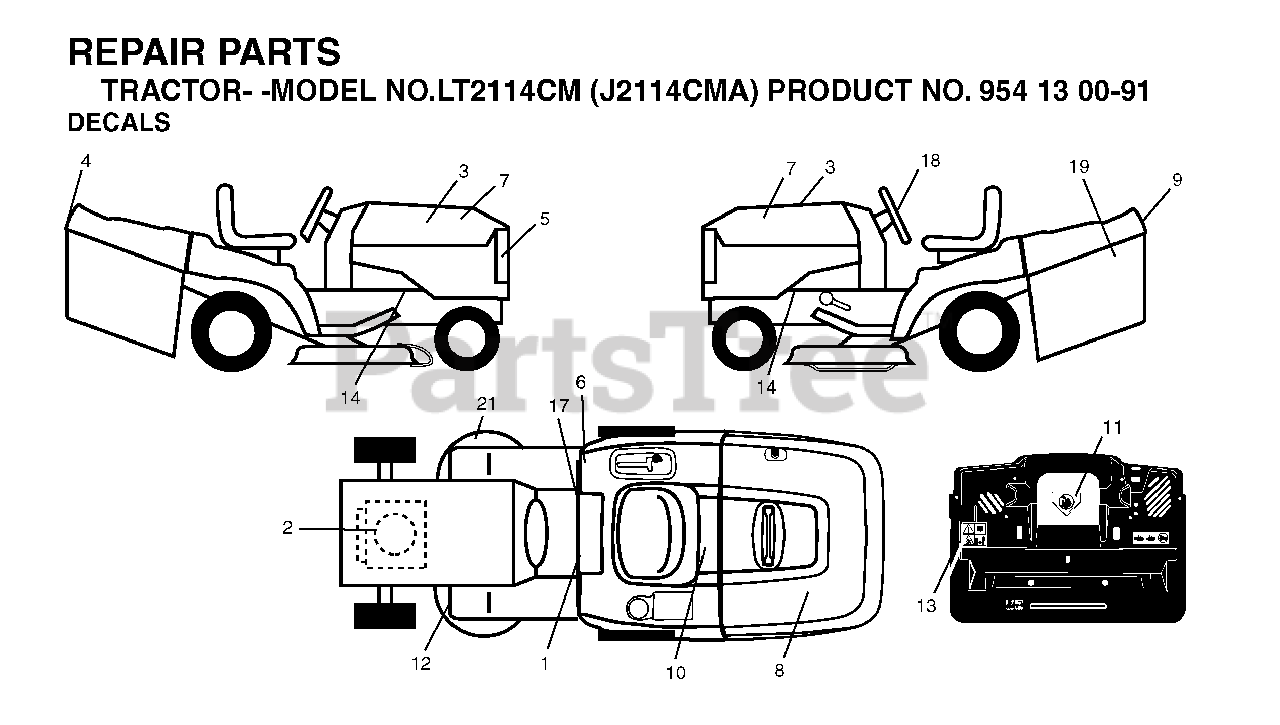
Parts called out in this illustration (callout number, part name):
1	DECAL READ OWNER'S MAN SYMS
10	DECAL BTRY SYMBOLS
11	DECAL.INTERNATIONL.CUTFINGER
17	DECAL PARK BRAKE
